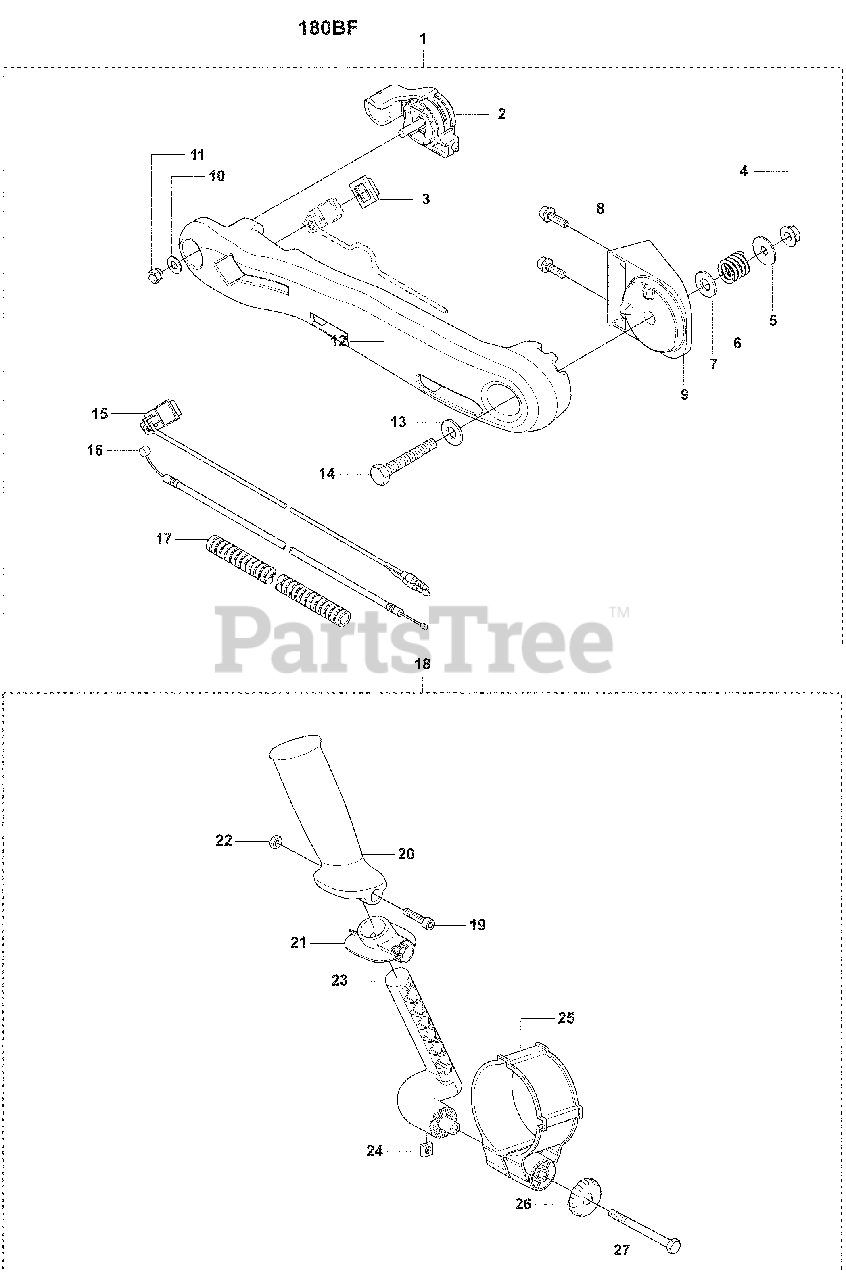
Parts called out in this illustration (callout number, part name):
1	Handle Assembly
2	Lever
3	Switch Cap
4	Nut
5	Washer
6	Spring
7	Washer
8	Screw
9	Bracket
11	Nut
12	ARM
13	Washer
14	Bolt
16	Cable, Complete
19	Screw
22	Hex Nut, M5 X .80 DIN
23	Holder
24	Square Nut
25	HOLDER TH
26	Air Filter Cover Knob
